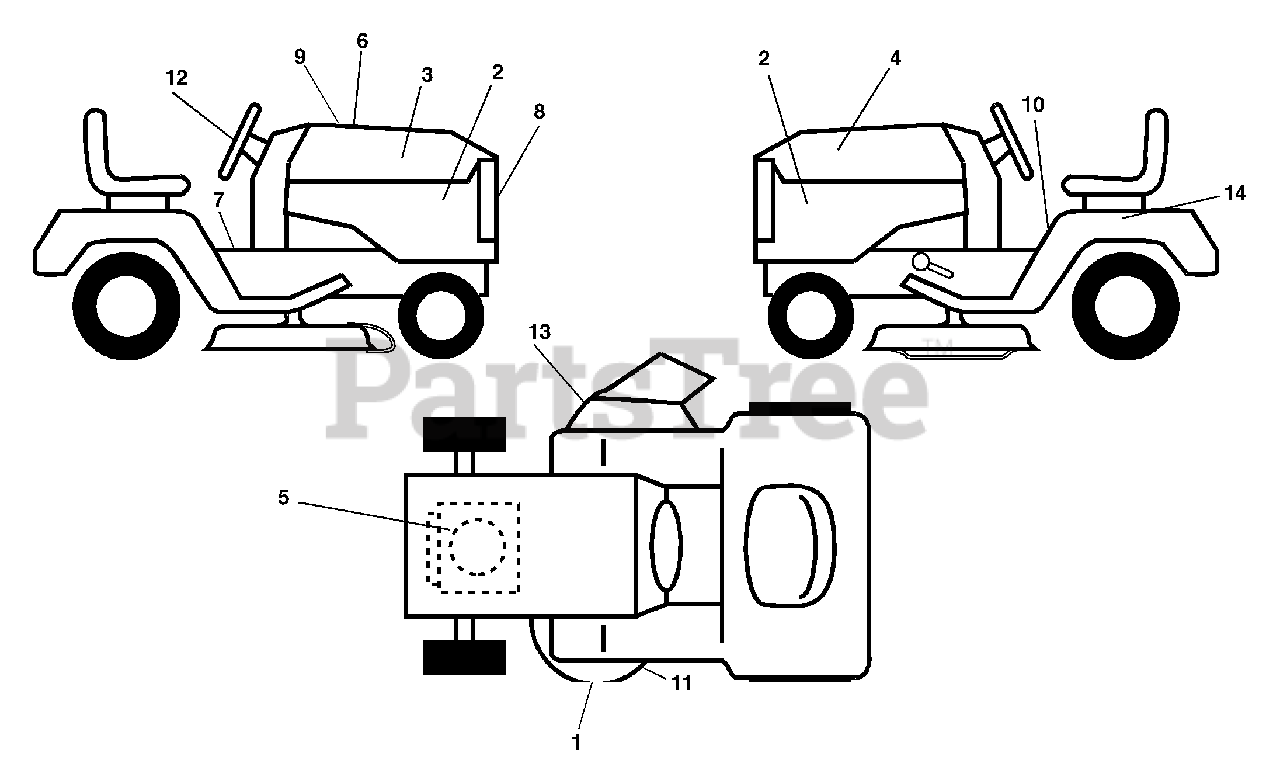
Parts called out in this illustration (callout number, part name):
1	Decal Deck Hvy Duty
2	Decal Panel Side
3	Decal Hood RH
4	Decal Hood LH
5	Decal HP Engine
6	Decal Hood Cust. Resp.
7	Decal Operator
8	Decal Dash
9	Decal Replacement
10	Decal Fender Danger
11	Decal V-Belt Sch.
12	Decal Wheel Steering
13	Decal Warning
14	Decal Bat Dan/Psn
